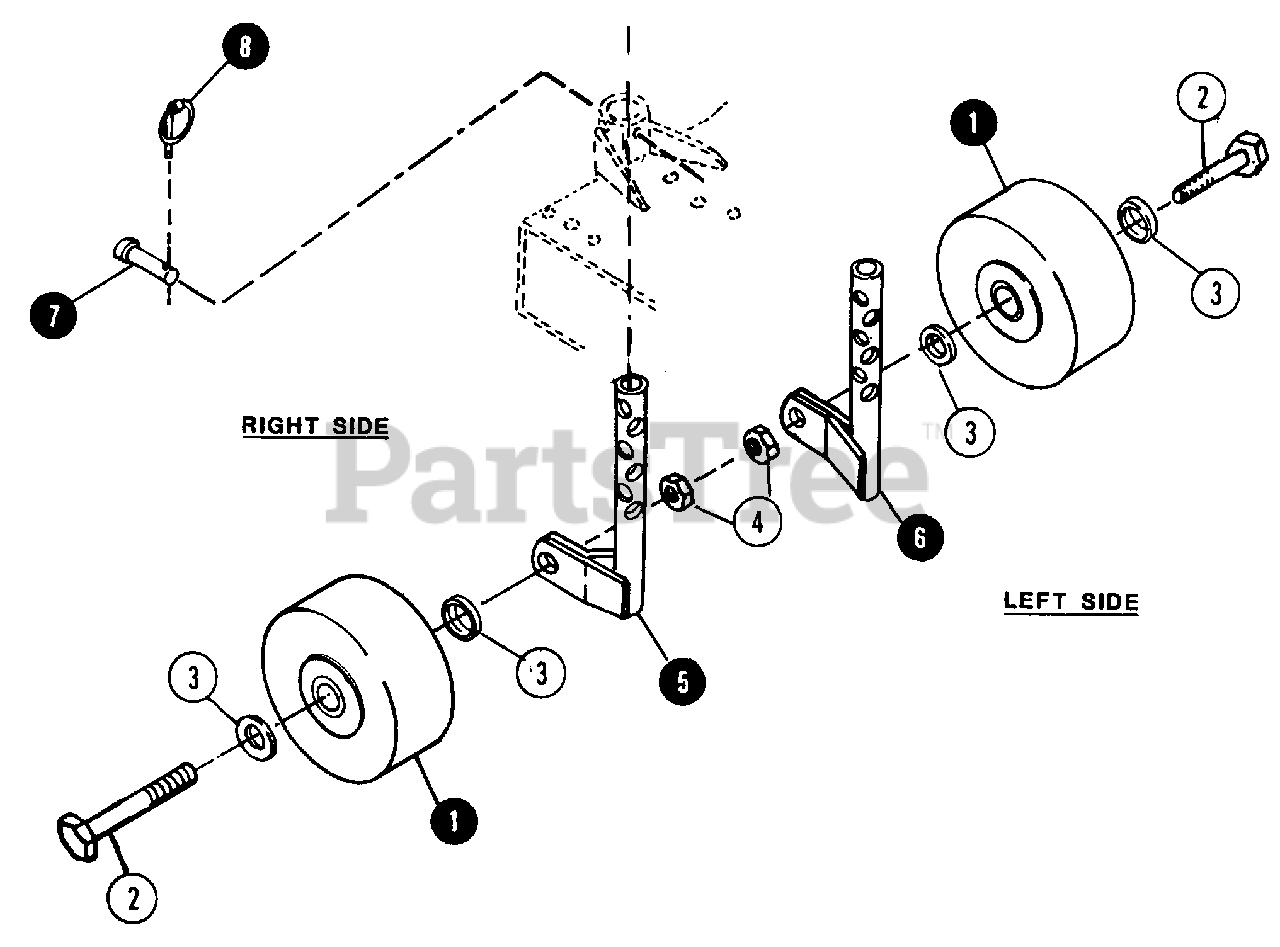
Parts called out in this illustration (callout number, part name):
1	WHEEL, GAUGE
2	BOLT, 1/2C x 3-1/2 HEX HEAD
3	CUP-WASHER, GAUGE WHEEL
4	NUT, 1/2C HEX
5	(NLA) SPINDLE, WHEEL - RIGHT SIDE (Use 7049870 & drill tube if necessary)
5	SPINDLE, WHEEL - RIGHT SIDE
6	SPINDLE, WHEEL - LEFT SIDE
7	CLEVIS-PIN, GAUGE WHEEL ADJUSTING
8	PIN, KLIK
